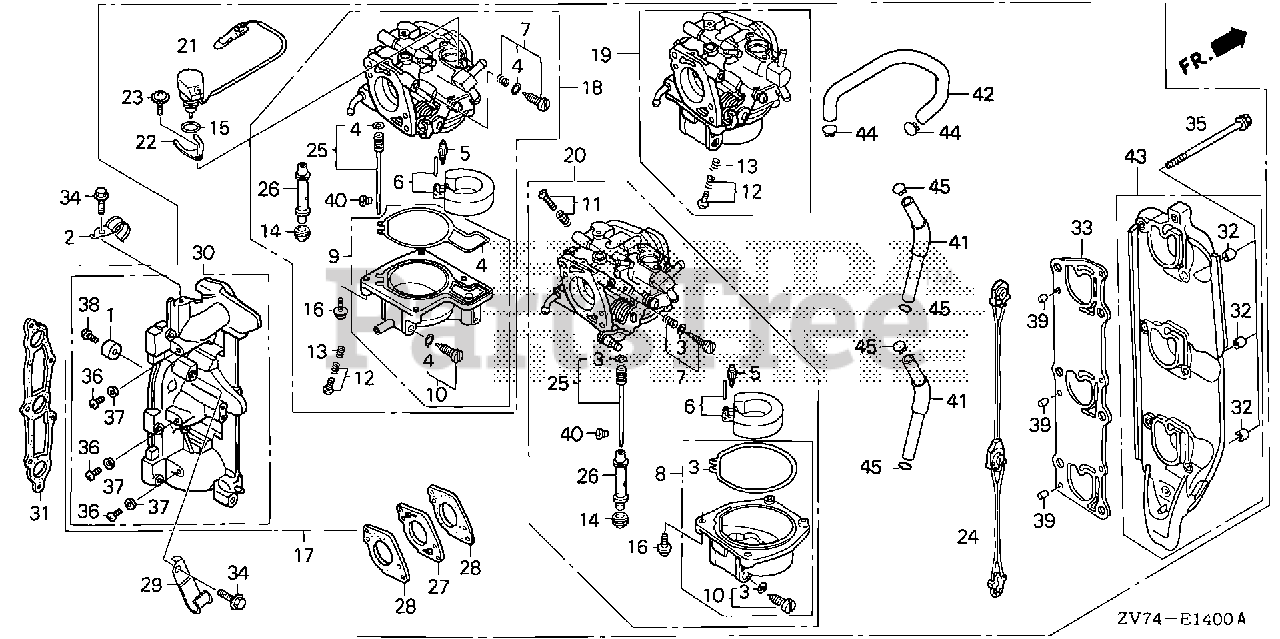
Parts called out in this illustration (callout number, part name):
1	METAL, ANODE
2	CLAMP, TUBE
3	GASKET SET
4	GASKET SET
5	VALVE SET, FLOAT
8	CHAMBER SET, FLOAT
9	CHAMBER SET, FLOAT (CARBURETOR NO.)
10	SCREW SET, DRAIN
13	SPRING, COMPRESSION COIL
14	SCREW, PLUG
15	O-RING, BYSTARTER
16	SCREW-WASHER
17	CARBURETOR ASSY. (BG10C F) *NH8* (DARK GRAY)
17	CARBURETOR ASSY. (BG10C G) *NH8* (DARK GRAY)
17	CARBURETOR ASSY. (BG13C D) *NH8* (DARK GRAY)
17	CARBURETOR ASSY. (BG13C E) *NH8* (DARK GRAY)
18	CARBURETOR ASSY. (#1) (CARBURETOR NO.)
21	BYSTARTER ASSY., AUTO (CARBURETOR NO.)
22	PLATE, SETTING
23	SCREW-WASHER
24	LEVER, LINK
25	JET SET (#42)
26	NOZZLE, MAIN (CARBURETOR NO.)
27	INSULATOR, CARBURETOR
28	GASKET, CARBURETOR
29	CLAMP, FUEL TUBE
30	MANIFOLD ASSY., IN. *NH8* (DARK GRAY)
31	GASKET, IN. MANIFOLD
32	COLLAR, DISTANCE
33	GASKET, MUFFLER PLATE (CARBURETOR NO.)
34	BOLT, FLANGE (6X12) (CT200)
35	BOLT, FLANGE (6X97)
36	SCREW, PAN (5X10)
37	WASHER, SEALING (5MM)
38	SCREW, PAN (6X18)
39	ROLLER (6X15)
40	JET, MAIN (#98)
40	JET, MAIN (#100)
40	JET, MAIN (#102)
40	JET, MAIN (#105)
42	TUBE, BYSTARTER (CARBURETOR NO.)
43	PLATE, MUFFLER (CARBURETOR NO.)
44	CLIP, TUBE (B10)
45	CLIP, TUBE (B12)
